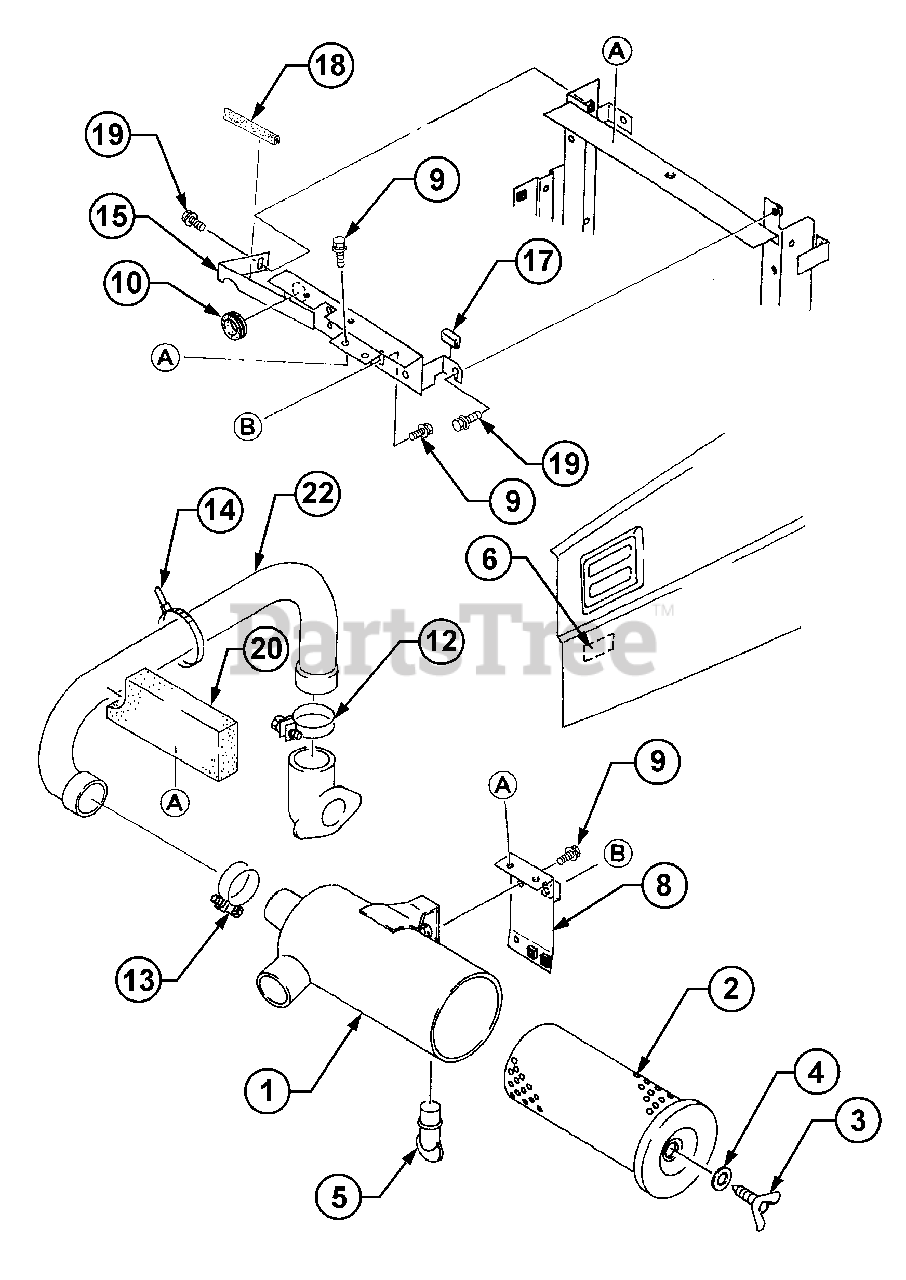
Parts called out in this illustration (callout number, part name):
1	Case Assy
6	Mark, Caution
8	Bracket, Cleaner
9	Bolt, w/Washer
19	Bolt, w/Washer
22	Hose, Air Cleaner
